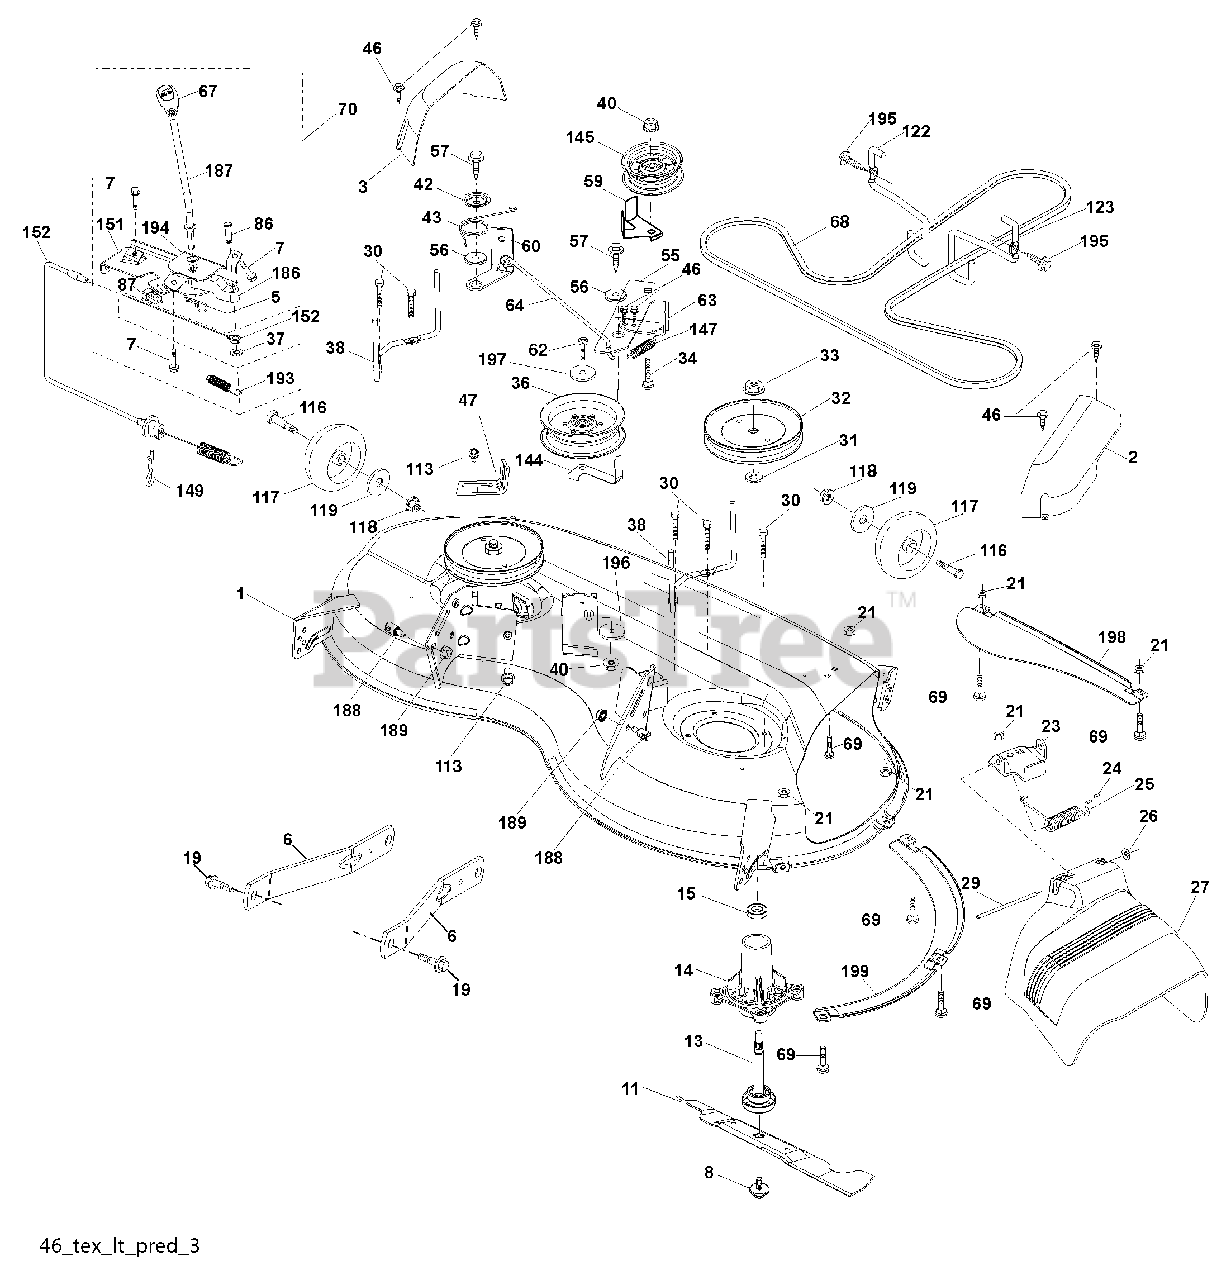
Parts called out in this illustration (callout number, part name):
1	Mower Housing
2	Cover Mandrel RH
3	Cover Mandrel LH
5	Retainer Spring
6	Arm Suspension
7	Screw 10 x 3/4 Single Hex
8	Bolt/Washer asm 7/16-20 unf
11	Blade Mower
13	Shaft Assembly, Mandrel
14	Housing, Mandrel
15	Bearing, Ball, Mandrel
19	Bolt, Shoulder
21	Nut
23	Bracket, Deflector
24	Cap, Sleeve
25	Spring, Torsion, Deflector
26	Nut, Push
27	Shield, Deflector
29	Rod, Hinge
30	Screw Thdrol Rolling Wsh Hd
31	Washer, Spacer
32	Pulley, Mandrel
33	Nut, Toplock, Flanged
34	Bolt Carr Sh. 3/8-16 x 1-1/2 Gr. 5
36	Pulley, Idler, Flat
37	Washer 13/32 x 13/16 x 16 Ga.
38	Keeper Belt LH Mandrel
40	Nut, Lock Flg. 3/8-16 unc
42	Spring Trosion Brake
43	Spring Torsion Retainer
46	Screw
47	Bracket Clutch Cable
55	Arm, Idler
56	Spacer, Retainer
57	Screw Hexwsh Thd 3/8-16 x 1
59	Guard, Tuv Idler (94)
60	Arm Brake Mower LH
62	Bolt 3/8-16 UNC x 2-1/4 Gr. 5
63	Arm Brake Mower
64	Linkage Brake
67	Handle, Clutch Cable
68	V-Belt
69	Bolt
70	Clutch Asm.
86	Pin Attachment Cable
87	Switch, Interlock Clutch
113	Screw 5/16-18
116	Bolt, Shoulder
117	Wheel, Gauge
118	Nut Centerlock 3/8-16 UNC
119	Washer 13/32 x 1-1/4 x 12 Ga.
122	Keeper Belt Eng. LH
123	Keeper Belt Eng. RH
144	Keeper Belt
145	Pulley Idler
147	Spring Return
149	Retainer Spring
151	Bracket Mount
152	Cable Clutch Manual w/Spr.
186	Arm Acutator CL Cable
187	Lever Control CL Cable
188	Stud Fastener
189	Nut Lock Hex Flange
193	Spring Plunger Actuator
194	Bearing Control Lever Clutch
195	Screw 3/8-16 x 3/4
197	Washer 13/32 x 13/16 x 12 Ga.
198	Baffle Center Front
199	Baffle Front RH
200	Washer 13/32 x 2 x 10 Ga.
200	Mandrel Assembly
200	Replacement Mower, Complete
